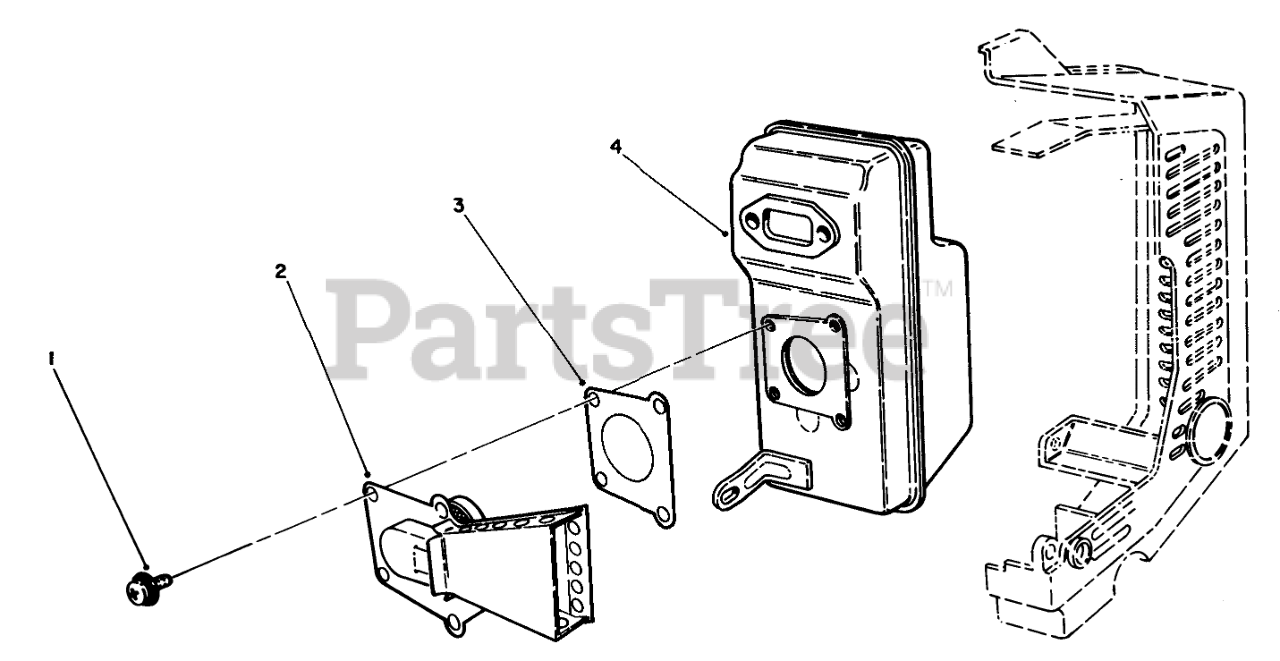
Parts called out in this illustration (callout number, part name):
1	Screw/Washer
2	Spark Arrester
3	GASKET
4	Muffler
